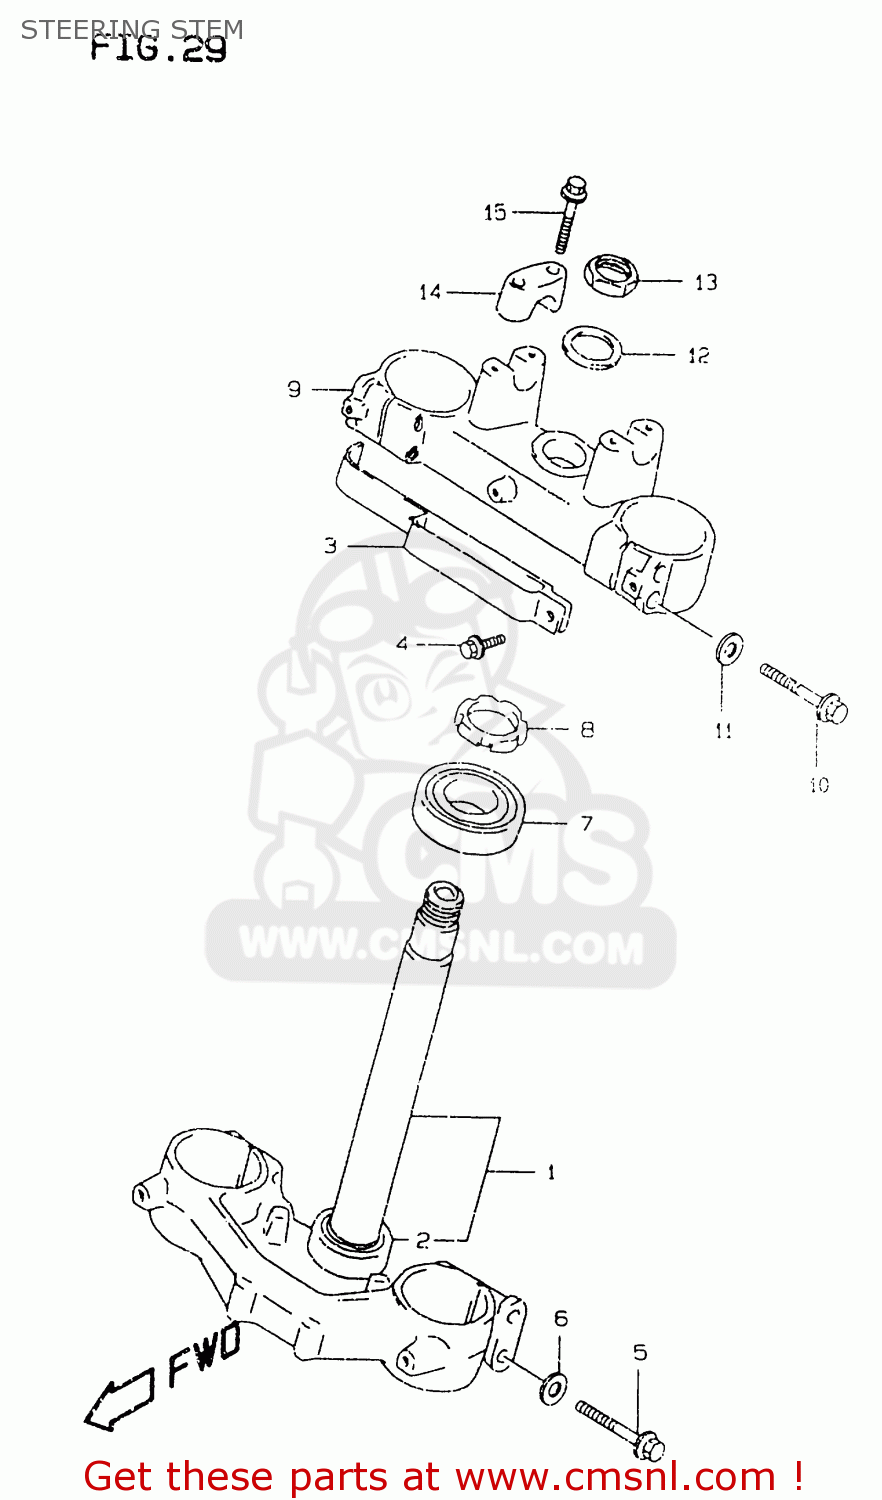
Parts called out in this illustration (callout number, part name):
1	STEM,STEERING
2	BEARING(30X52X16)
3	GUIDE,FR BRAKE HOSE
4	BOLT,PROTECTOR(6X10)
5	BOLT
6	WASHER
7	BEARING(30X52X16)
8	NUT,STEERING
9	HEAD,STEERING STEM
10	BOLT
11	WASHER
12	WASHER,STEM HEAD
13	NUT,STEM HEAD
14	HOLDER,HANDLEBAR
15	BOLT,HANDLE HOLDER(8X35)
